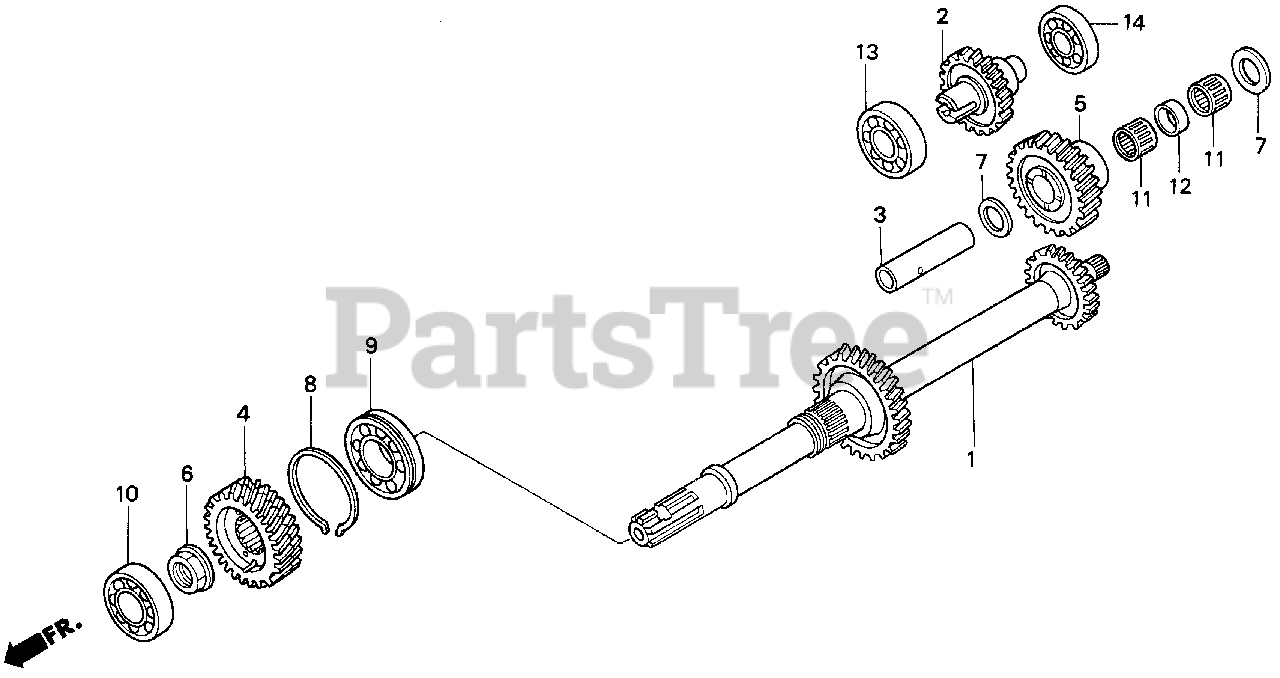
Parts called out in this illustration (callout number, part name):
1	SHAFT, INPUT
2	SHAFT, PUMP DRIVE
3	SHAFT, PUMP IDLE
4	GEAR ASSY., PRIMARY
5	GEAR, PUMP IDLE (31T)
6	NUT, LOCK (25MM)
7	WASHER, THRUST (17X22X0.75)
8	RING, SNAP (58MM)
9	BEARING, SPECIAL BALL (62/28)
10	BEARING, RADIAL BALL (62/22)
11	BEARING, NEEDLE (19X23X13)
12	COLLAR, DISTANCE (20X23X12.7)
13	BEARING, RADIAL BALL (6204)
14	BEARING, RADIAL BALL (6203)
